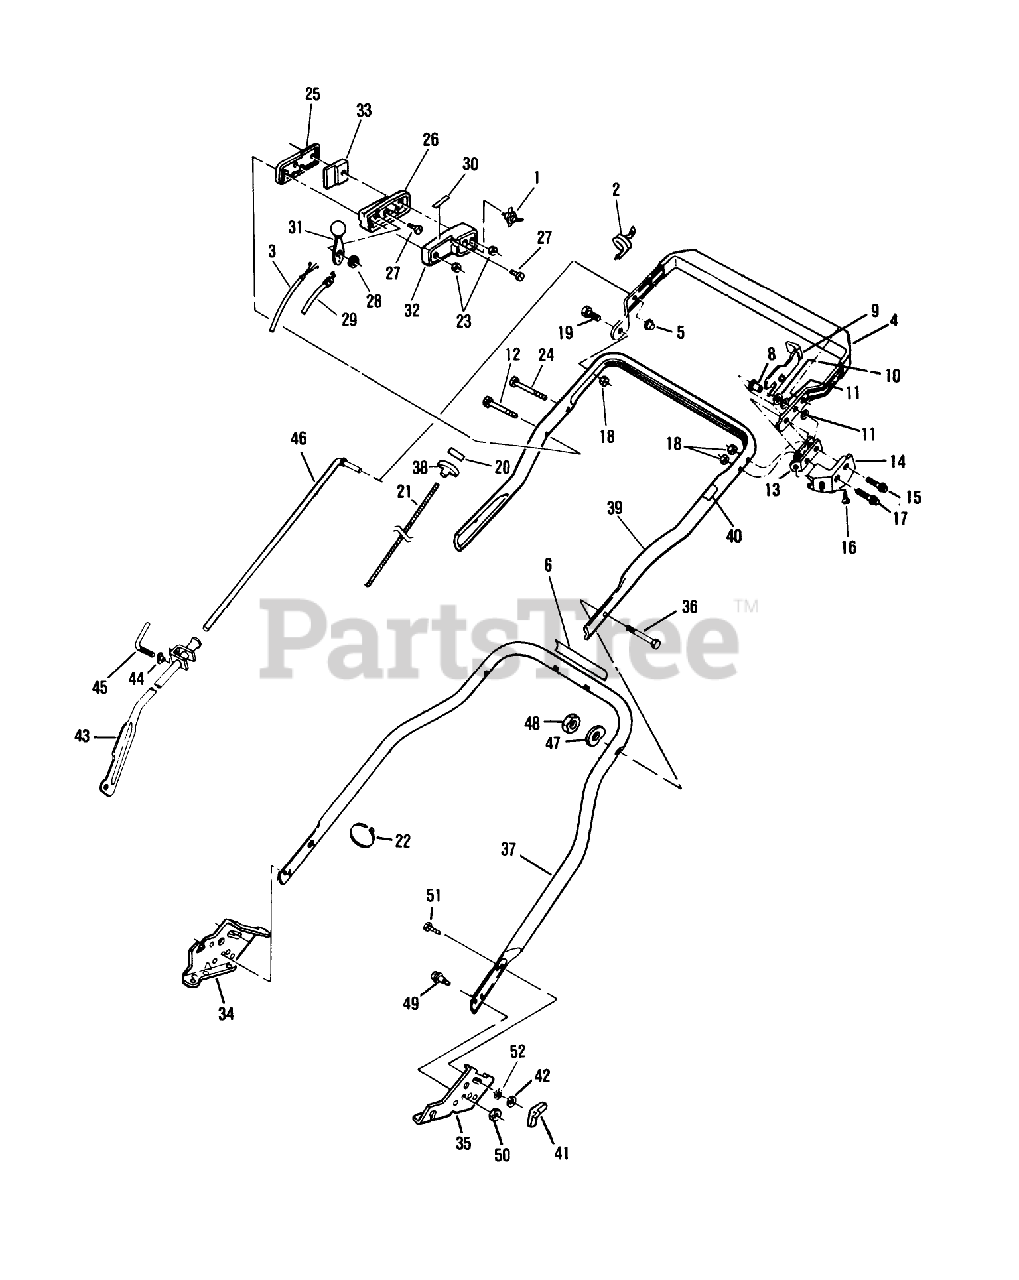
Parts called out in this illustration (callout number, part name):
8	SPACER
10	WASHER M
12	SCREW
13	DOWN STOP
15	BOLT SHOU
16	SCREW F
17	SCREW
18	LOCKNUT E
19	BOLT
20	CLIP-STARTER
23	NUT C/LOCK E
25	OUTER CONTROL CASE
27	SCREW
28	WASHER-SPRING
29	CABLE THROT WES
31	LEVER&KNOB AY WES
41	NUT-WING
42	WASHER
43	CONTROL LEVER AY
46	CONTROL ROD
47	WASHER-CURVED
48	NUT-LOCK F
49	BOLT
50	NUT-JAM, LOCKING
52	LOCK WASHER LARSON
